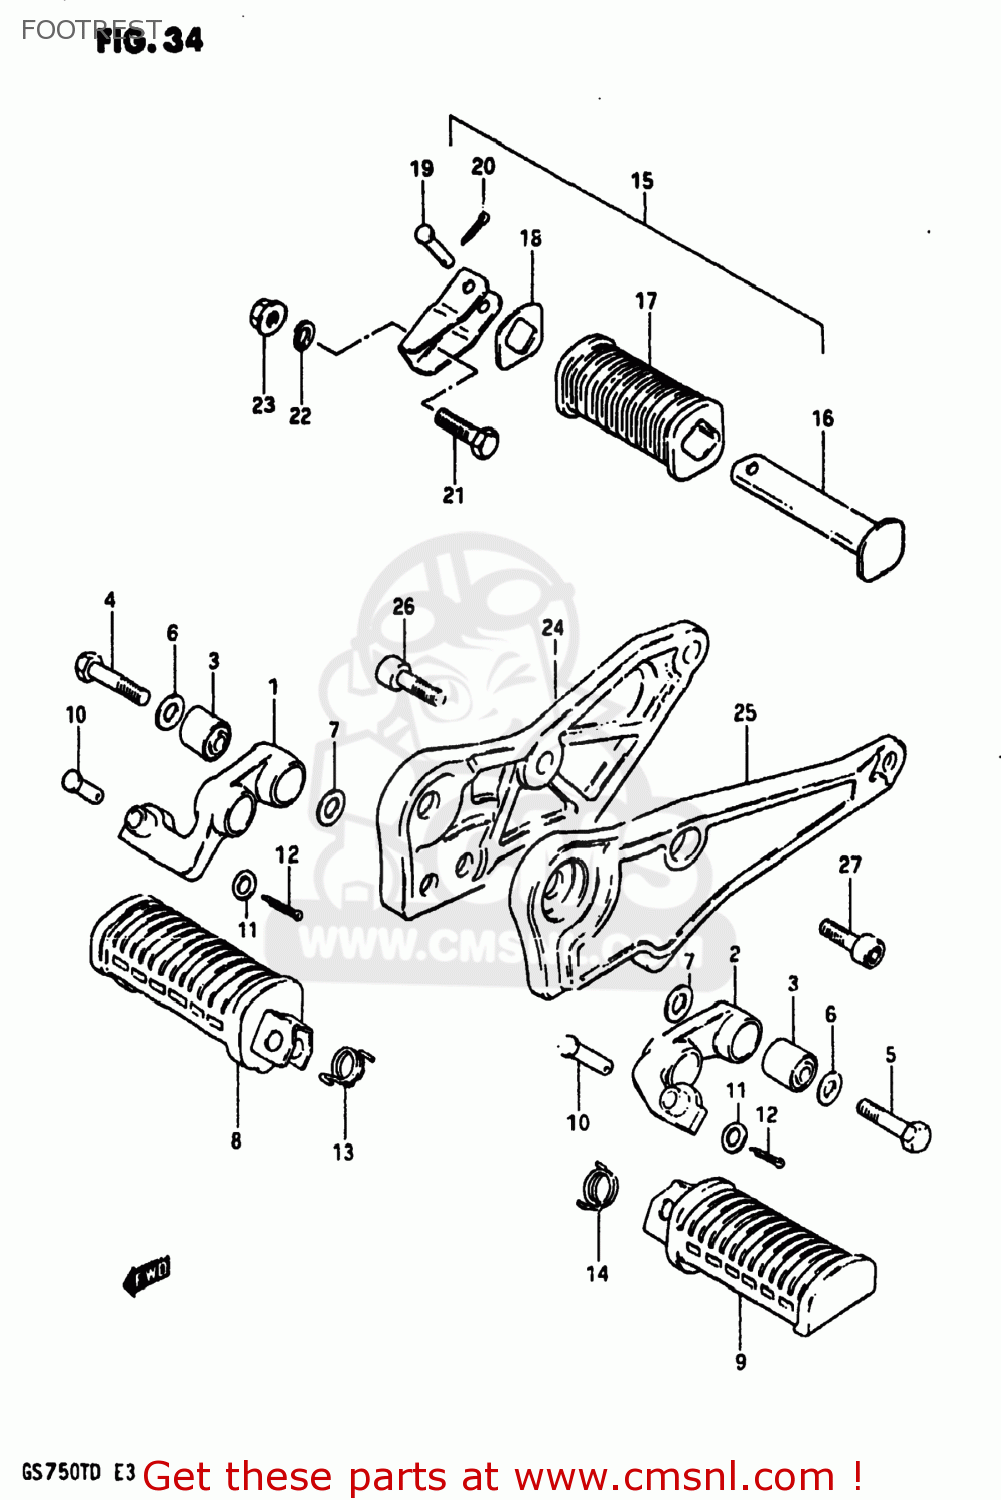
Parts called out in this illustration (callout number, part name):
1	BAR,FRONT FOOTREST,RIGHT
2	BAR,FRONT FOOTREST,LEFT
3	BUSH
4	BOLT(10X50)
5	BOLT
6	WASHER
7	WASHER
8	RUBBER,FOOTREST
9	FOOTREST
10	PIN
11	WASHER
12	PIN 20X20
13	SPRING
14	SPRING
15	FOOTREST ASSEMBLY,REAR
16	BAR,REAR FOOTREST
17	RUBBER,REAR FOOTREST
18	WASHER,REAR FOOTREST RUBBER
19	PIN
20	PIN 20X20
21	BOLT,M10X1.25X
22	LOCK WASHER
23	NUT
24	BRACKET,MUFFLER,RIGHT
25	BRACKET
26	BOLT
27	BOLT
